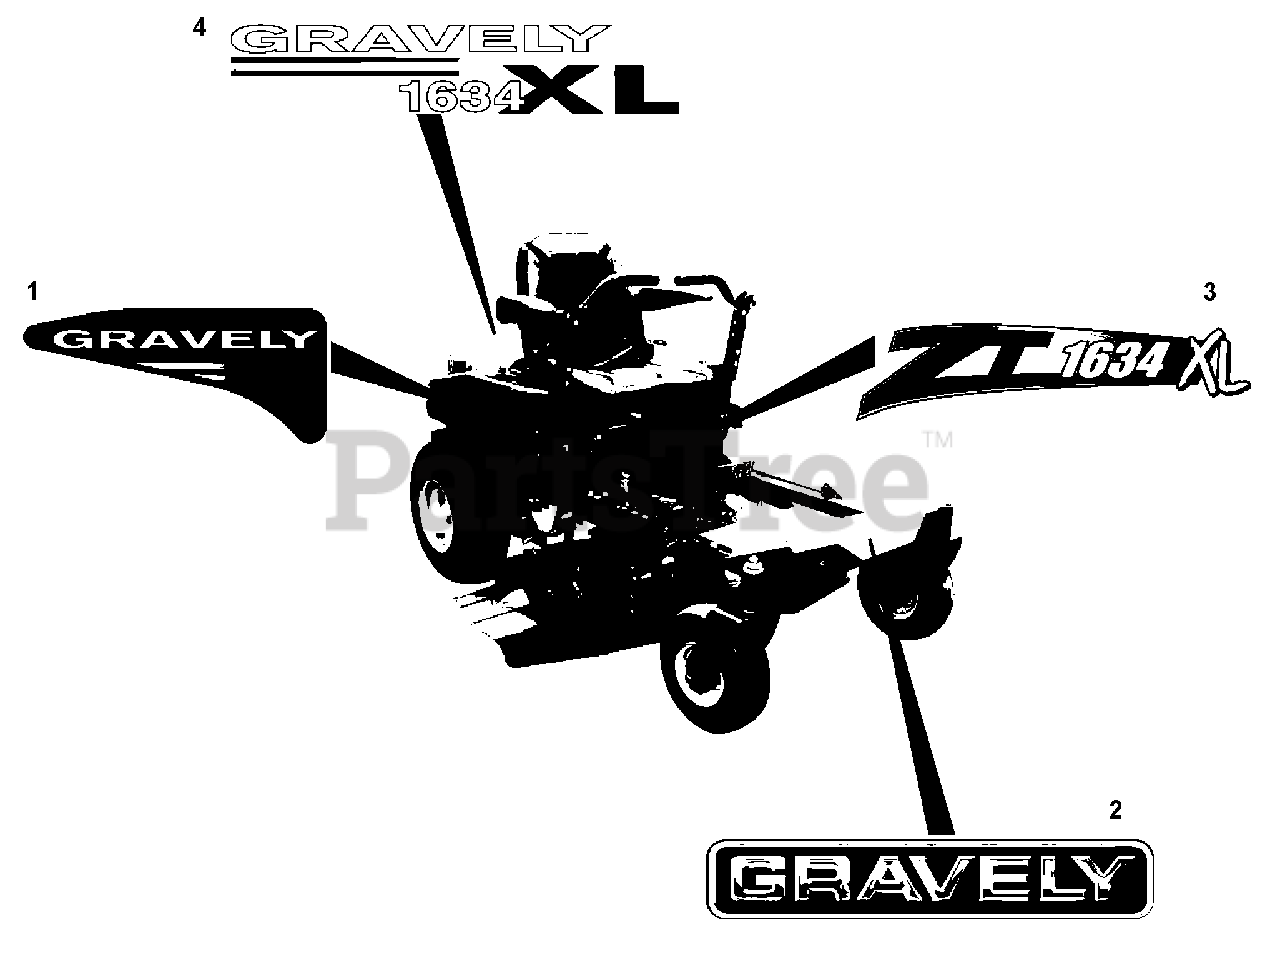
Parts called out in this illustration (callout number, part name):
1	Decal, Gravely ZT XL RH Fender
2	Decal, Gravely Logo
3	Decal, Gravely 1634 ZT XL
4	Decal, Gravely ZT XL Hood
